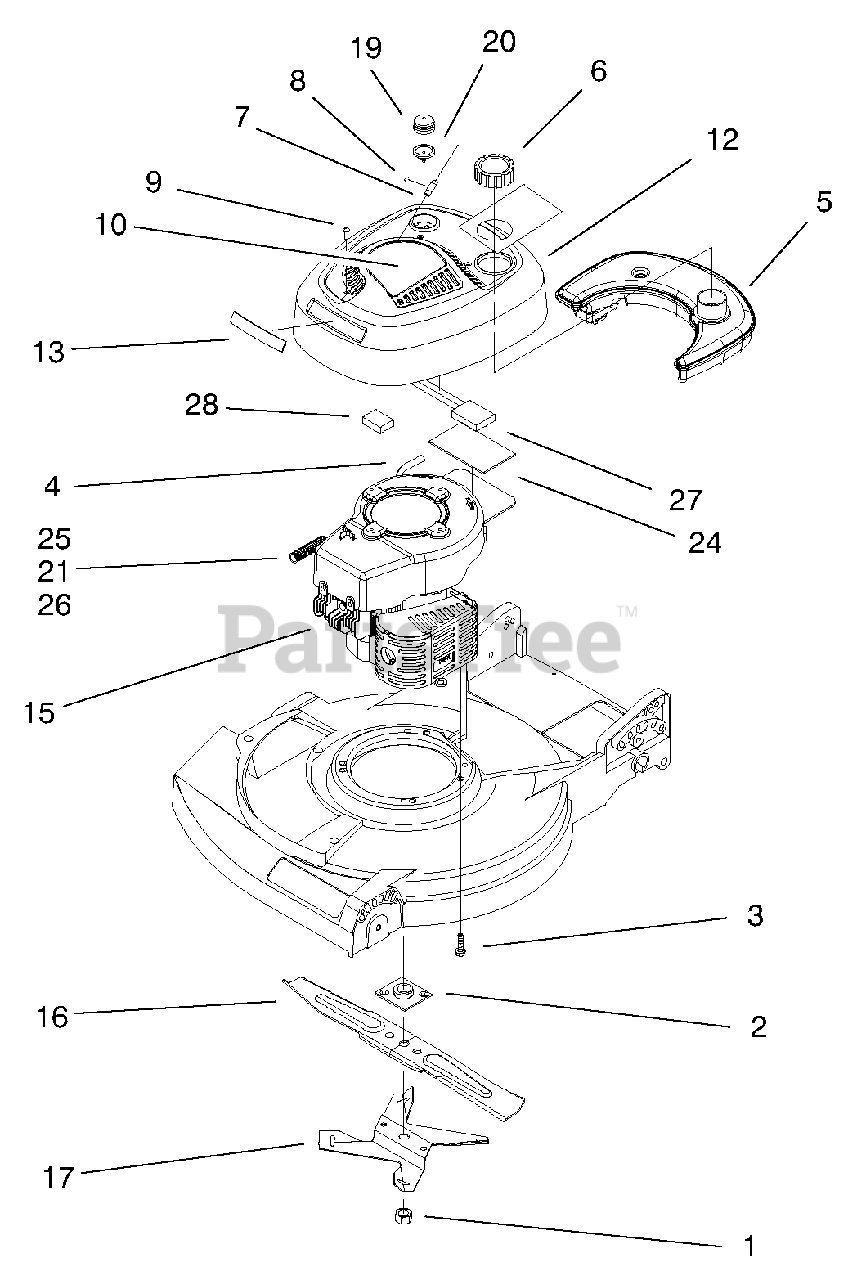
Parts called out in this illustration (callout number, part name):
1	Nut-Blade
2	ASM-Plate & Collar
3	Screw-Sems
4	Gas Line
5	Gas Tank
6	ASM-Fuel/Oil Cap
7	Rope Stop
9	Screw-Tf Acorn Hd
10	Decal-Recoil
12	ASM-Shroud Electric
13	Applique-Shroud
15	Engine ASM Re Cst Hsg Sp
16	Blade-21" Whirl
17	Fan-Mulching
19	Bulb-Primer
20	Body-Primer
22	Screw-Throttle Cable
23	Nut-Throttle Cable
24	Foam Pad
25	Lever-Brake
26	Retainer
27	Foam Strip
28	Foam Strip
